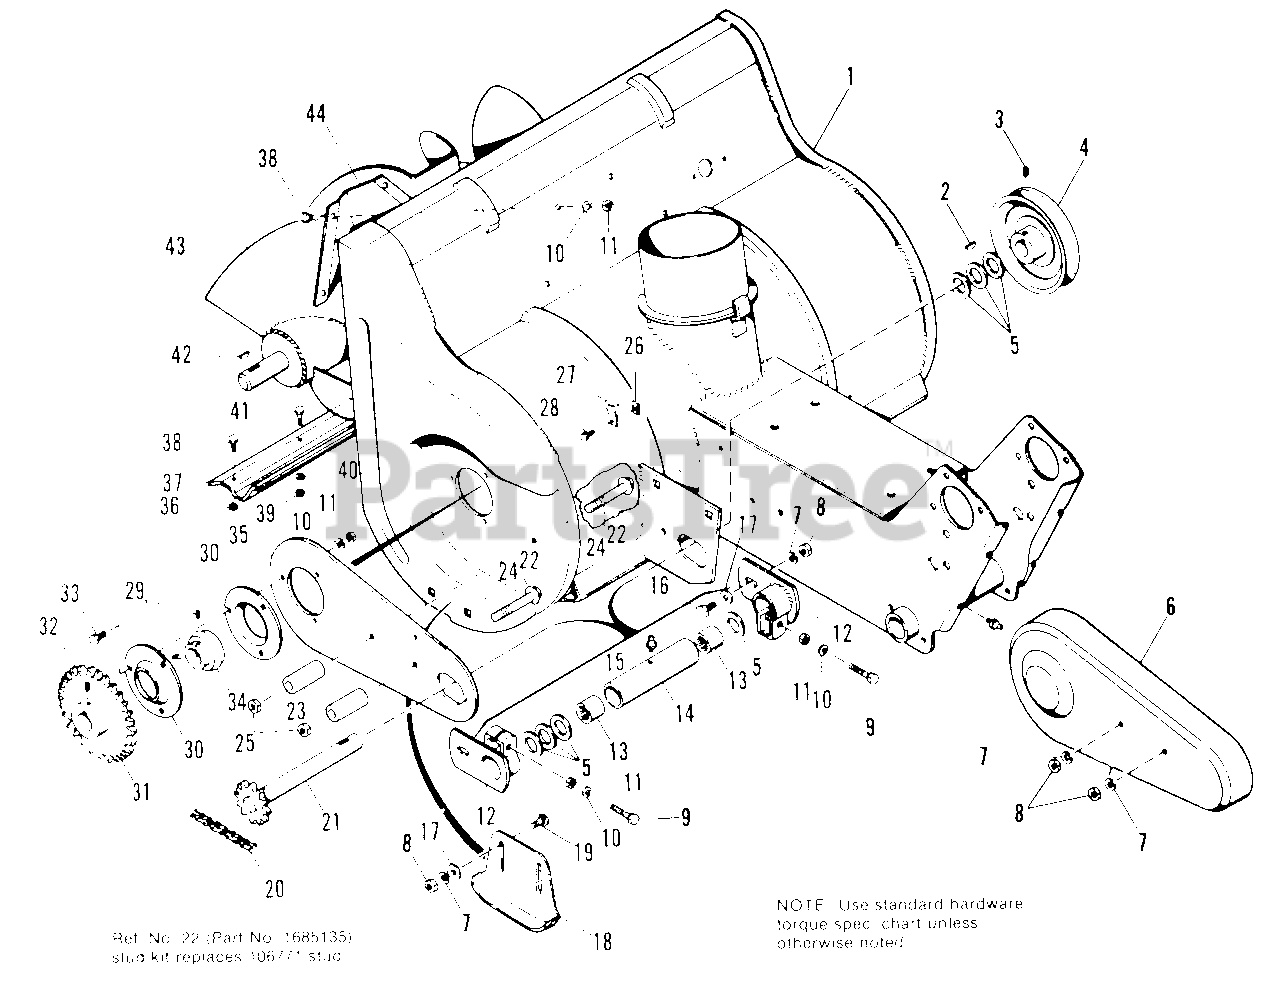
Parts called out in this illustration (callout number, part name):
1	BODY ASSY., Frame (990483 & 990559 Only)
1	BODY ASSY., Frame (990482 Only)
1	BODY ASSY., Frame (990558 & 1690305 Only)
2	KEY, Woodruff, #9
3	SETSCREW, 5/16-18 x 5/16
4	PULLEY (990482, 990483, 990558 & 990559 Only)
4	PULLEY (1690305 Only)
5	WASHER (Qty. 2 used on 1690305)
6	GUARD, Chain (990482, 990483, 990558 & 990559 Only)
6	GUARD, Chain (1690305 Only)
7	LOCKWASHER, 3/8 (Qty. 6 used on 1690305)
8	NUT, Hex, Full, 3/8-16 (Qty. 6 used on 1690305)
9	CAPSCREW, Hex Hd., 5/16-18 x 1-1/2 (Qty. 1 used on 1690305)
10	LOCKWASHER, 5/16 (Qty. 8 used on 1690305)
11	NUT, Hex, Full, 5/16-18 (Qty 8 used on 1690305)
12	CLAMP, Housing (Qty. 1 used on 1690305)
13	BEARING, Needle
14	HOUSING ASSY., W/Bearings (990483 & 990559 Only)
14	HOUSING ASSY., W/Bearings (990482, 990558 & 1690305 Only)
15	FITTING, Grease (990483 & 990559 Only)
16	CAPSCREW, Hex Hd., 3/8-16 x 1 (Qty. 1 used on 1690305 Only)
17	WASHER, Plain, 3/8 (Qty. 5 used on 1690305)
19	BOLT, Carriage, 3/8-16 x 3/4
21	SHAFT ASSY. (990483 & 990559 Only)
21	SHAFT ASSY. (990482, 990558 & 1690305 Only)
22	STUD KIT (Includes Ref. Nos. 23, 24 & 25)
24	SCREW, Flange, Whiz, 3/8-16 x 2-1/4
25	LOCKNUT, Flange, 3/8-16
26	NUT, Speed (990482, 990483, 990558 & 990559 Only)
27	CLIP, Speed (990482, 990483, 990558 & 990559 Only)
28	SCREW, Self Tapping, #10 x 1/2 (990482, 990483, 990558 & 990559 Only)
29	SETSCREW, 1/4-28 x 1/4 (990482, 990483, 990558 & 990559 Only)
30	FLANGE, Bearing
32	SETSCREW, 5/16-18 x 1/2
33	CAPSCREW, Hex Hd., 5/16-18 x 3/4
34	BEARING, Cartridge (990482, 990483, 990558 & 990559 Only)
34	BEARINGS, Cartridge (1690305 Only)
35	PLATE, Side (990482, 990483, 990558 & 990559 Only)
35	PLATE, Side (1690305 Only)
36	LOCKNUT, Hex, 5/16-18
37	SCRAPER, Body (990483 & 990559 Only)
37	SCRAPER, Body (990482, 990558 & 1690305 Only)
38	CAPSCREW, Hex Hd., 5/16-18 x 5/8
39	NUT, Hex, Full, 1/4-20
40	LOCKWASHER, 1/4
41	CAPSCREW, Hex Hd., 1/4-20 x 5/8
42	KEY, Hi-Pro
43	ROTOR ASSY. (990483 & 990559 Only)
43	ROTOR ASSY. (990482, 990558 & 1690305 Only)
